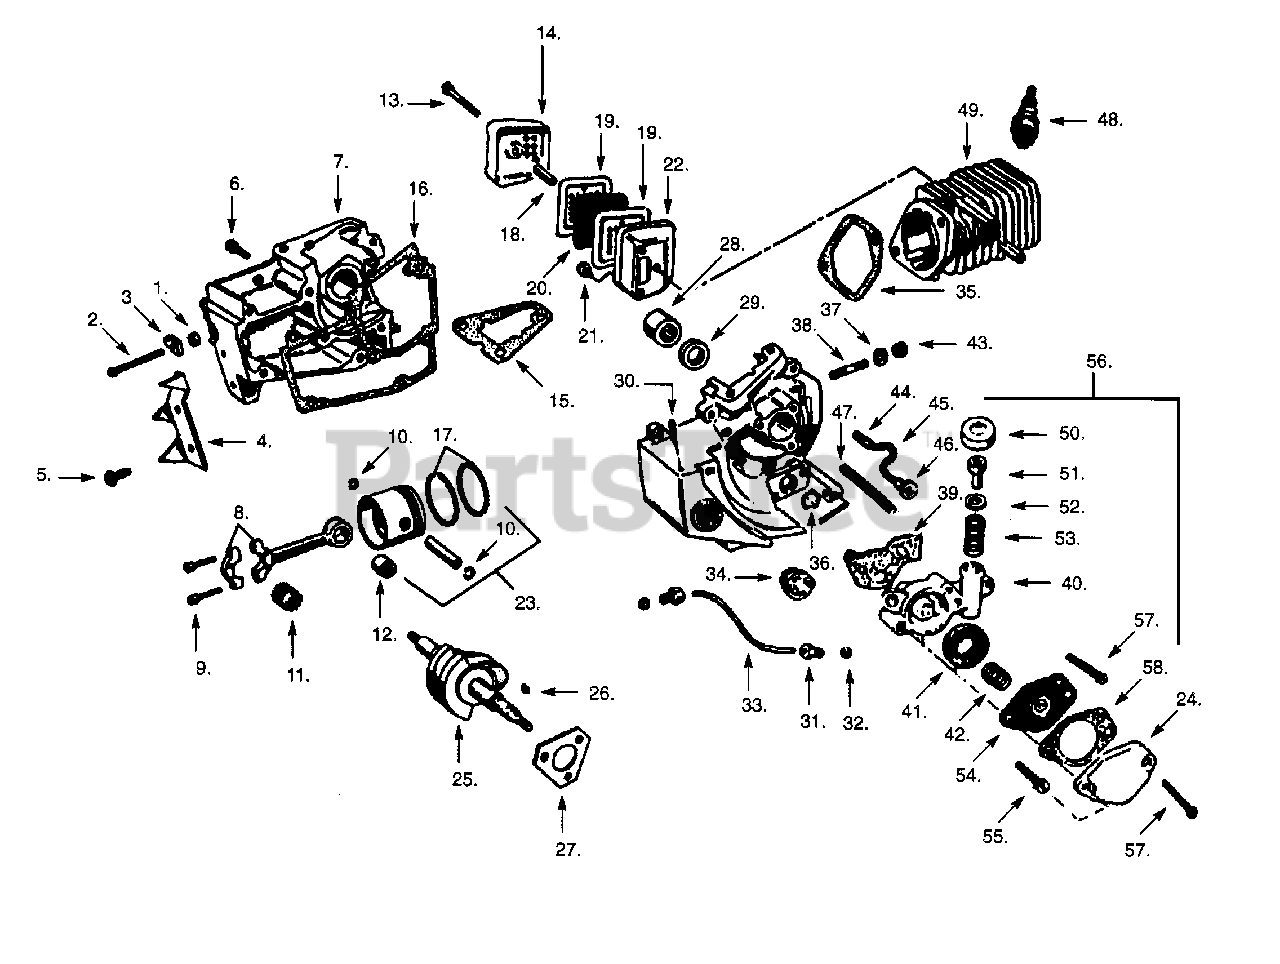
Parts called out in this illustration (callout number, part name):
2	Screw
3	Bar Adjusting Pin
4	Spur (Optional)
7	Crankcase Ass'y.
8	Connecting Rod Ass'y.
10	Piston Pin Retainer
11	Crankpin Rollers
12	Piston Pin Bearing
14	Muffler Cover
15	Gasket
16	Crankcase Gasket
17	Piston Rings
18	Muffler Spacer
19	Muffler Baffle
20	Muffler Screen
22	Muffler Body
23	Piston Ass'y.
24	Oil Pump Cover
25	Crankshaft
26	Flywheel Key
27	Crankcase Washer
29	Seal
30	Oil Vent Pin
31	Discharge Line Fit ting
32	Ferrule 1/8" Tubing
33	Discharge Line-Oil Pump (Bulk 8115)
34	Oil Cap
35	Cylinder Gasket
37	Cylinder Washer
38	Cylinder Studs
39	Oil Pump Body Gasket
40	Oil Pump Body
41	Pump Body Filter
42	Diaphragm Spring
44	Oil Pick-up Weight
45	Oil Line (Bulk 8132)
46	Oil Pump Intake Valve
47	Oil Line Protector Spring
48	Spark Plug
49	Cylinder
50	Oil Pump Cap
51	Oil Pump Plunger
52	Quad Ring Plunger
53	Oil Pump Spring
54	Diaphragm Ass'y.
56	Pump Ass'y.
58	Pump Body Cover Gasket
